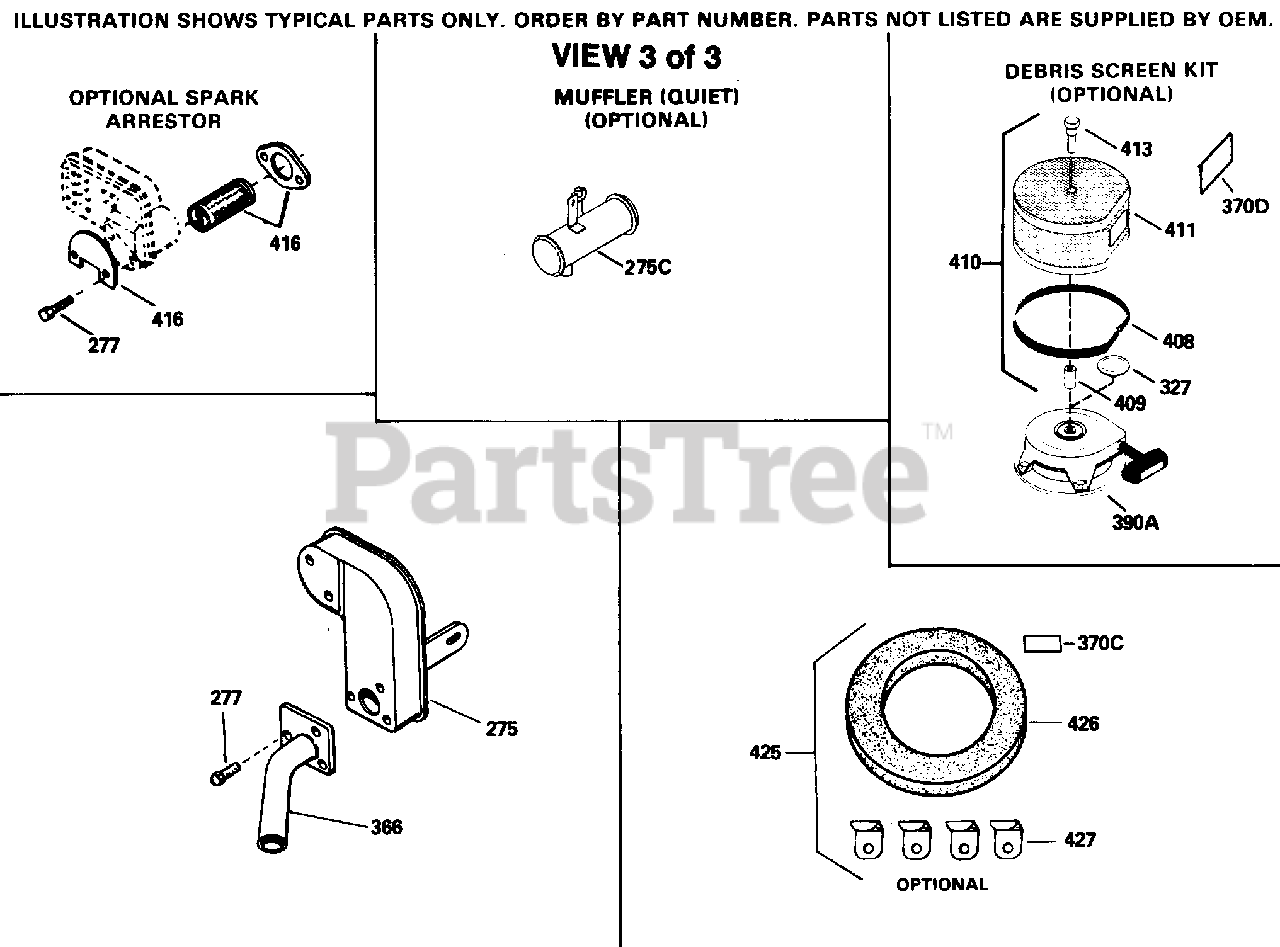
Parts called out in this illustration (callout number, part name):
275C	Muffler (Quiet) (Optional)
277	Screw, 5/16-18 x 3/4" .)
277	Screw, 5/16-18 x 3-3/16" Use As Req.
277	Screw, 5/16-18 x 4-3/16" Use As Req.
327	Plug, Screen
370C	Decal, Instruction (Optional)
370D	Decal, Instruction (Optional)
408	Screen Seal (Optional)
409	Spacer (Optional)
410	Opt.Screen Kit Incl. 370D,408,409,411 , 413
411	Debris Screen (Optional)
413	Screw, 5/16-18 x 1-5/8" (Optional)
416	Spark Arrestor Kit (Optional)
425	Starter Muff Kit (Incl. 370C,426,427) O pt.
426	Starter Air Cleaner (Optional)
427	Starter Air Cleaner Bracket (Optional )
